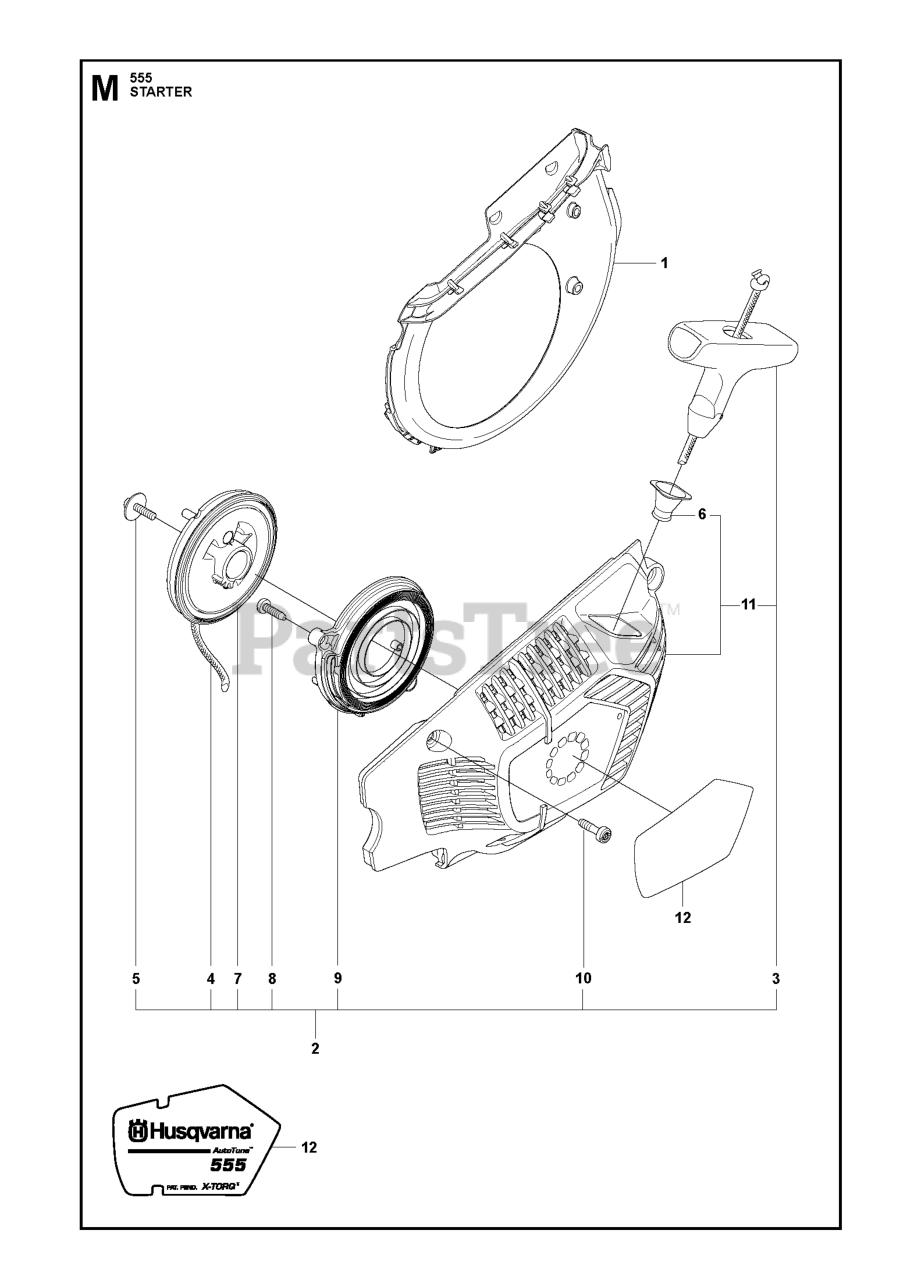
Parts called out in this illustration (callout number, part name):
1	COOLING AIR CONDUCTOR
4	STARTER ROPE
5	SCREW ITXSCT MT5X16 10.9 TBO
7	STARTER PULLEY ASSY
8	SCREW CITXPANT
10	SCREW CITXPANMO
11	STARTER HOUSING
